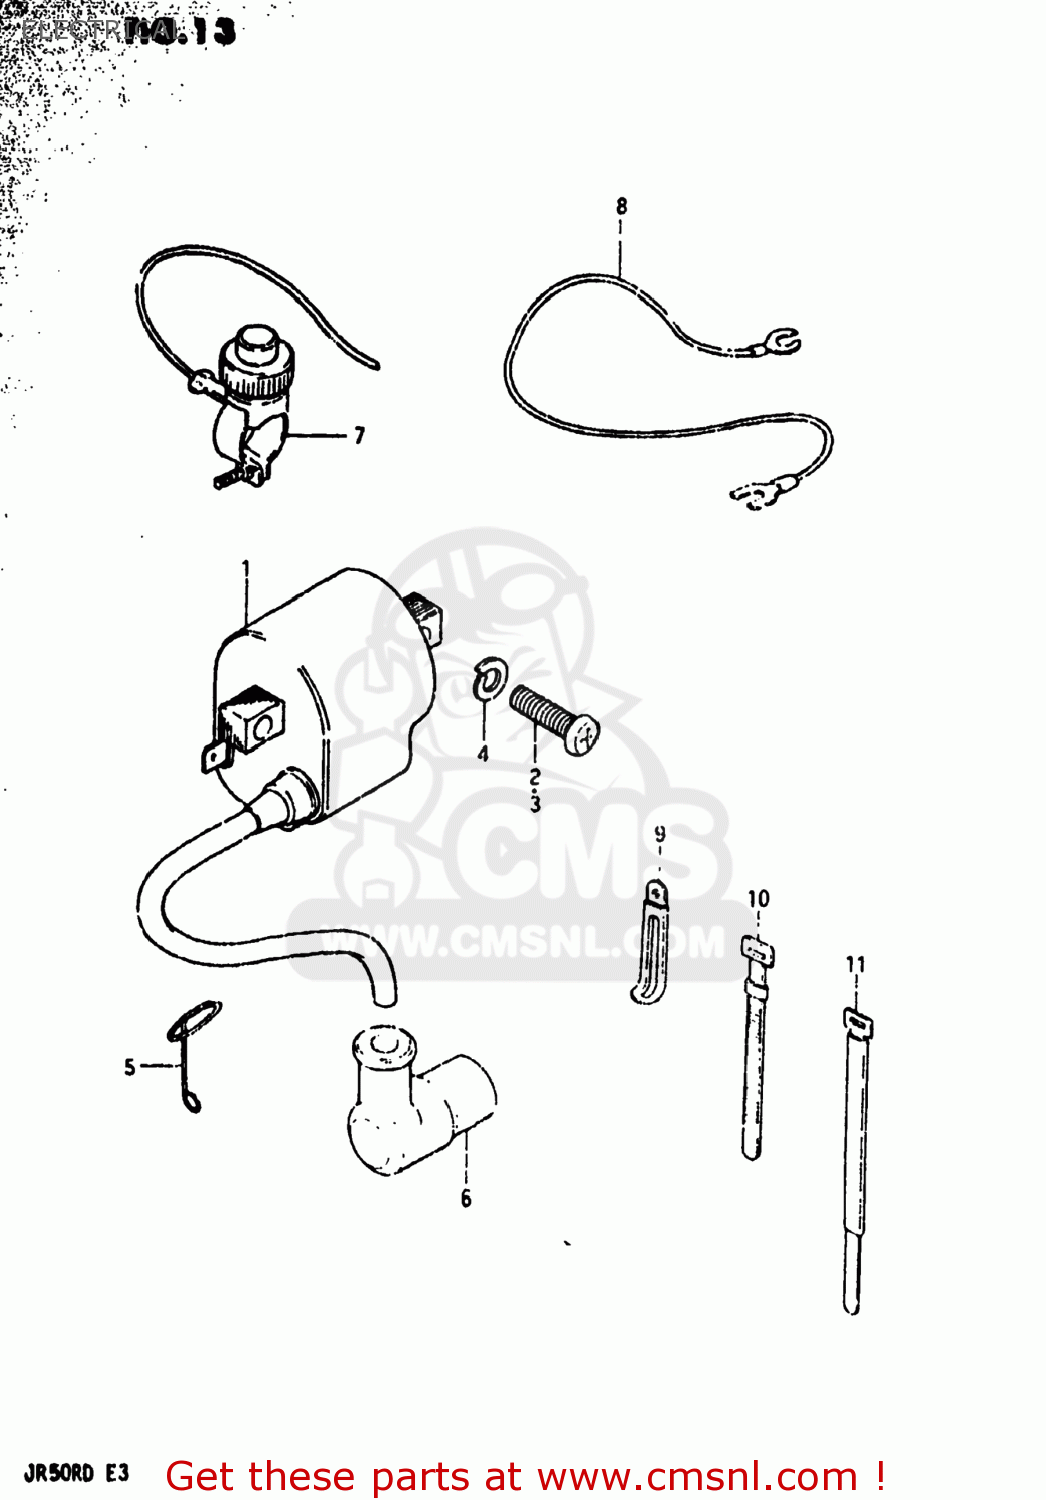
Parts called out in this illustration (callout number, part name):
1	COIL ASSEMBLY,IGNITION
2	SCREW
3	SCREW
4	LOCK WASHER
5	CLIP
6	CAP,SPARK PLUG
7	SWITCH ASSEMBLY
8	WIRE
9	CLAMP
10	CLAMP(L:120)
11	CLAMP
